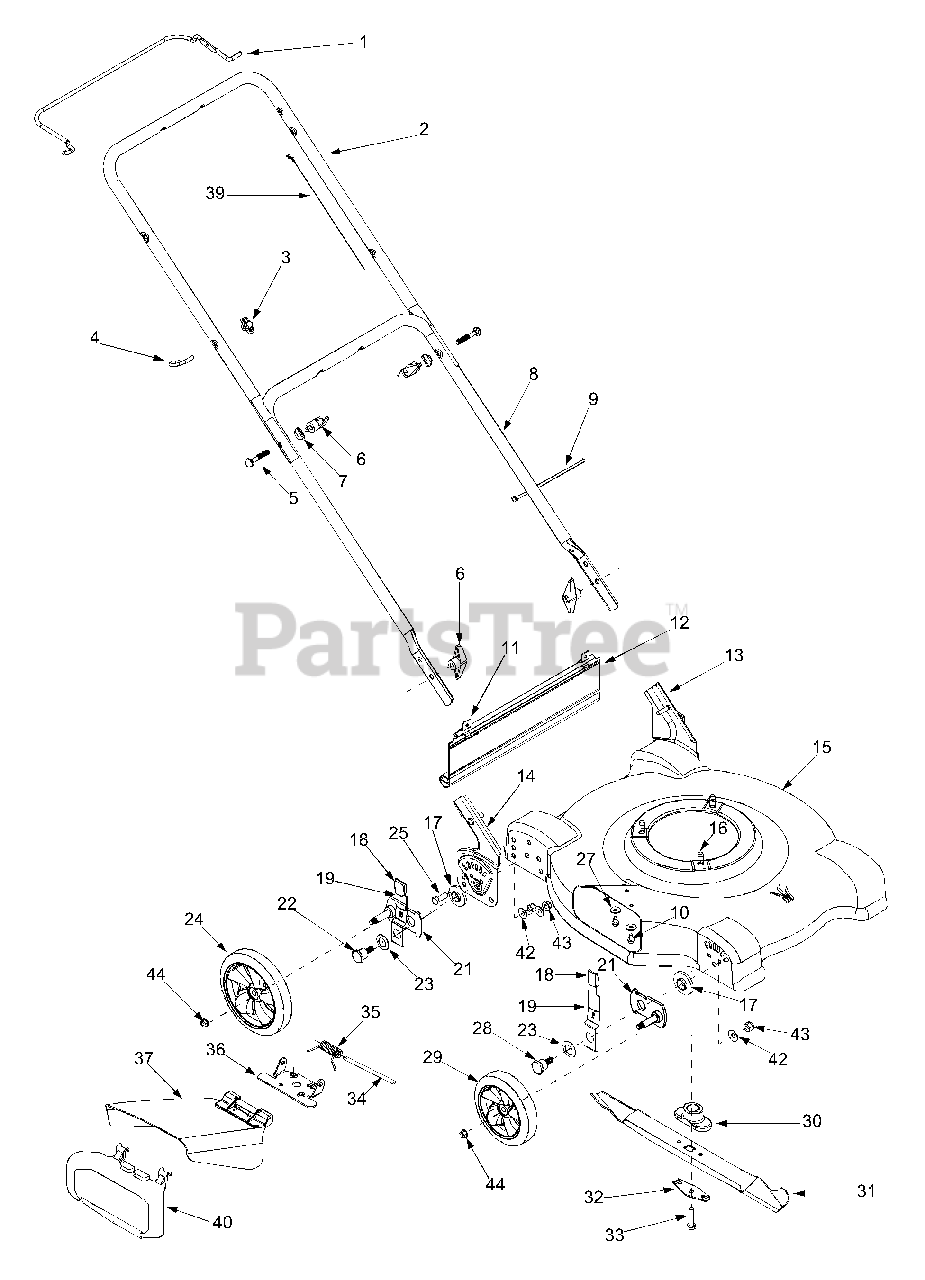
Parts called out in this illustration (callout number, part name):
3	Wing Nut
4	Eye Bolt
5	Carriage Bolt 5/16-18 x 2.0
6	Wing Nut
7	Shoulder Washer .320 ID x .93 OD
9	Cable Tie
10	TT Screw 1/4-20 x 0.5"
11	Hinge Clip
12	Trail Shield
16	TT Screw 3/8-16 x 1.0
17	Height Adjuster Bearing
18	Height Adjuster Knob
19	Lever Assembly
20	Hex Cap Screw 3/8-16 x .75
21	Pivot Arm
22	Shoulder Screw
23	Bell Washer .760 ID x 1.25 OD
24	Rear Wheel 8 x 1.8
25	Hex Cap Screw 3/8-16 x 1.0
27	Bell Washer .265 ID x .75 OD
28	Shoulder Screw
29	Front Wheel 7 x 1.8
30	Blade Adapter
31	Standard Blade 22"
32	Blade Bell Support
33	Hex Cap Screw 3/8-24 x 1.5
34	Hinge Pin
35	Torsion Spring
36	Chute Hinge
37	Hinged Chute Deflector
39	Blade Control Cable - 37.25"
40	Mulching Plug (if equipped)
42	Washer Spacer .401 ID x .870 OD
43	Hex Lock Nut 3/8-16
44	Lock Nut 3/8-16
